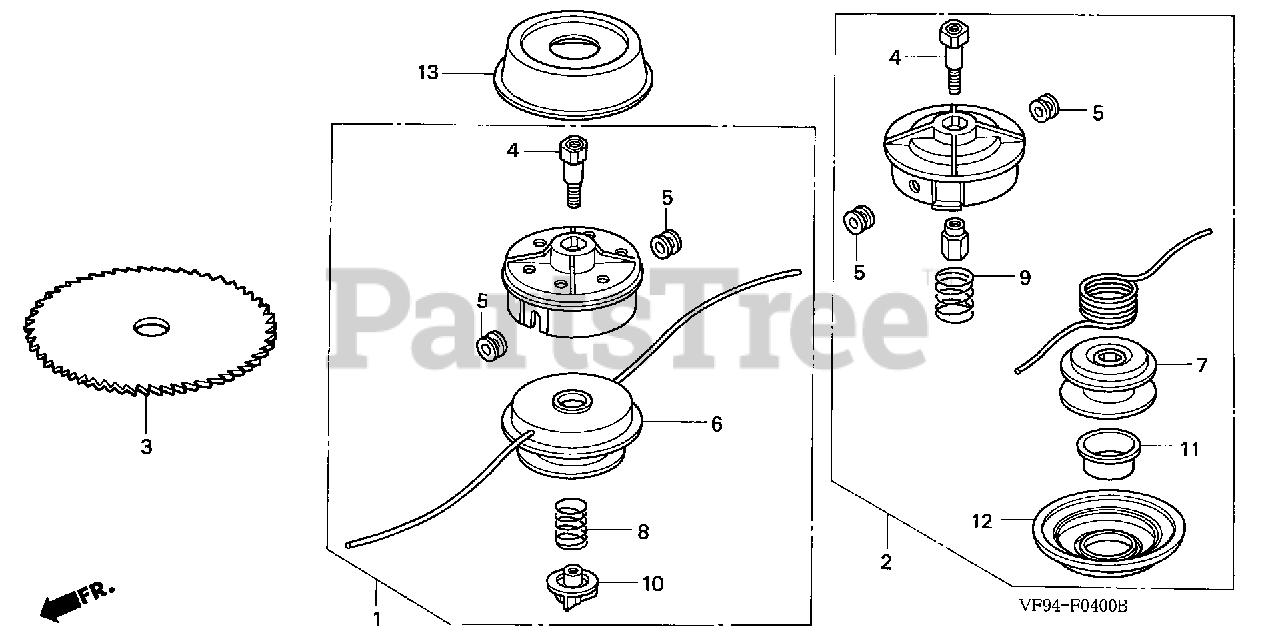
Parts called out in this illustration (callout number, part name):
1	CUTTER ASSY., NYLON
1	TRIMMER HEAD, MANUAL POP
4	SHAFT (10X1.25) (LH)
6	SPOOL
13	GUARD B, GRASS
